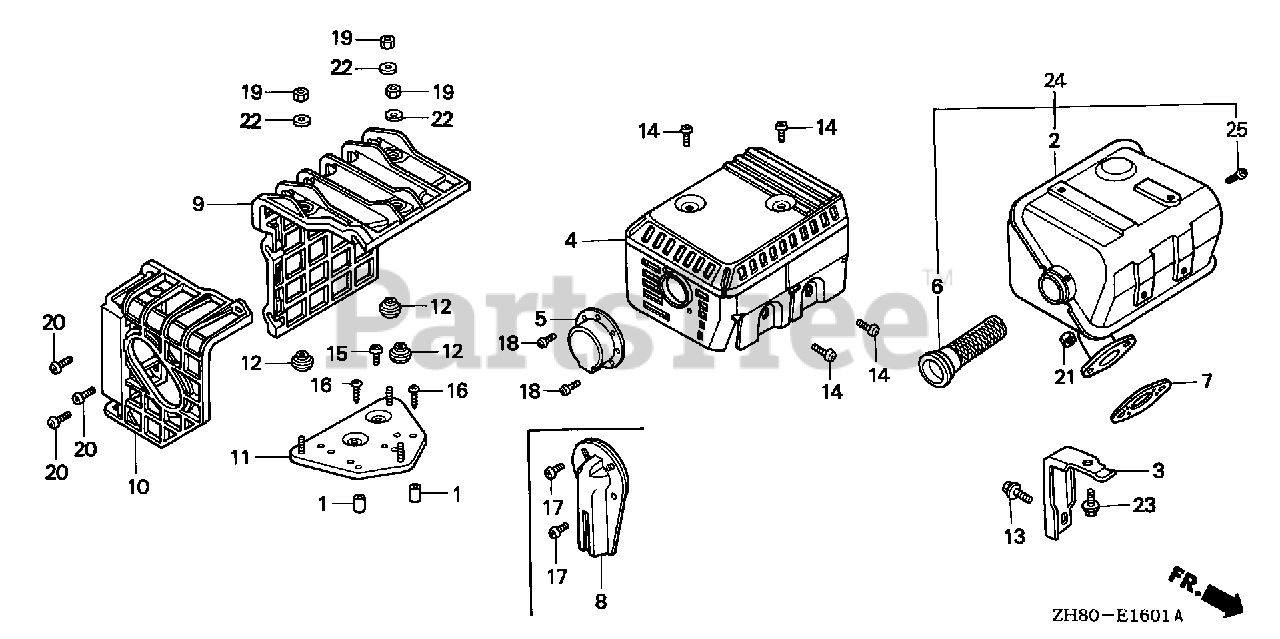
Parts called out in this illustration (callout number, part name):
2	MUFFLER (STD)
2	MUFFLER (ARRESTER)
4	PROTECTOR, MUFFLER (STD) (BLACK)
6	ARRESTER, SPARK
7	GASKET, MUFFLER
14	SCREW, TAPPING (5X8)
21	NUT, HEX. (8MM)
25	SCREW, TAPPING (4X6)
